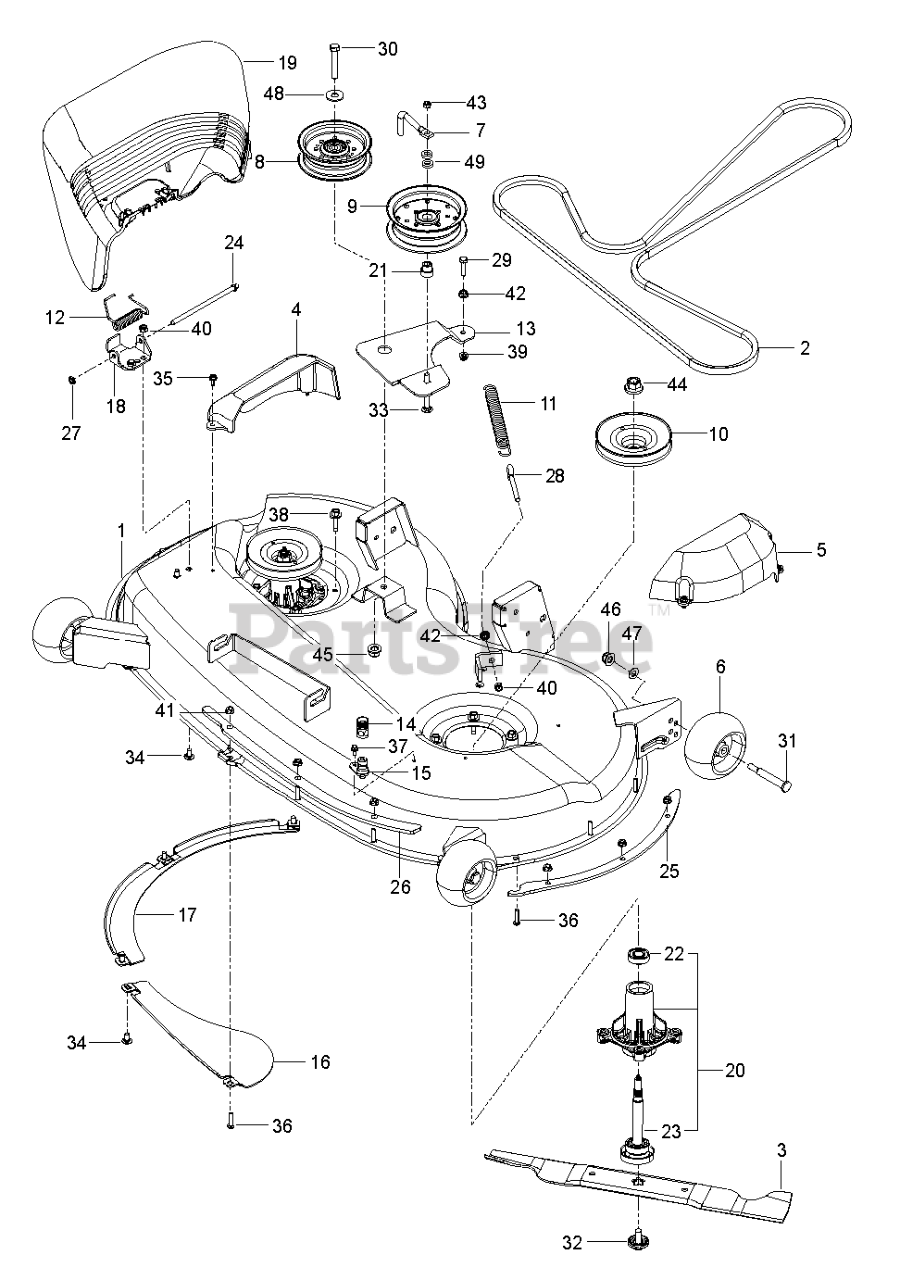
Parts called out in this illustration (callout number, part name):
1	DECK SVC 46"W/DECALS ORG
3	BLADE.MOWER.46".HI.LIFT
4	COVER.MANDREL.RH.46"
6	WHEEL.GAUGE.RALLY
7	BELT KEEPER 5"
8	PULLEY.IDLER.MWR.STATI.LH
9	PULLEY.IDLER.DECK
10	PULLEY.MANDREL.46"
11	SPRING.EXTENSION
12	SPRING, TORSION
13	ARM.PNT.CLTCHG.STMP.46.RZ.EDIP
14	COUPLING.QUICK CONNECT
15	PORT.WASHOUT
16	BAFFLE CENTER FRONT
17	BAFFLE FRONT RH
18	BRKT.DEFLECTOR.38"2005+
19	SHIELD.DEFLECTOR.MOWER.46"BLAC
20	MANDREL.W/SPCR.BRG.SHRT.NONRVL
21	IDLER BUSHING
22	BEARING.MANDREL.TOP.EXTENDED
23	SHAFT
24	ROD.HINGE
25	PLATE.REINFOR.46.SIDEBOLT.X431
26	PLATE.PNT.REINF.DECK.46".EDIP
27	NUT PUSH M
28	EYE BOLT 5/16 X 3.50
29	BOLT.5/16-18X1-1/4 FULL THD
30	BOLT.HEX.7/16-14
31	BOLT.SHOULDER.3/8-16X3-5/8.
32	SCREW.SEMS.7/16-20X1.HEX.HEAD
33	BOLT CARRIAGE
34	BOLT 5/16C X 3/4" CARRIAGE
35	SCREW.1/4-20X5/8
36	SCREW.BUTTONHEAD.1/4-20X1
37	SCREW #10 X 1/2 SELF TAPPING
38	BOLT.HEX.WASHR.HED.313-18X1.19
39	5/16-18 NYLOC FLANGE NUT
40	NUT.71038.31-18.HEX.NYLOCK
41	NUT T
42	NUT 5/16C WHIZ
43	NUT HEX 3/8-16 NYLON, THIN
44	NUT.FLANGE.LOCK.TOP
45	NUT.LOCK.FLANGE.7/16
46	NUT LOCK FLG 3/8-16 UNC
47	WASHER 5/16 FLAT
48	WASHER 7/16 FLAT ZD
49	WASHER 3/8 X 3/4 X .187 TK
